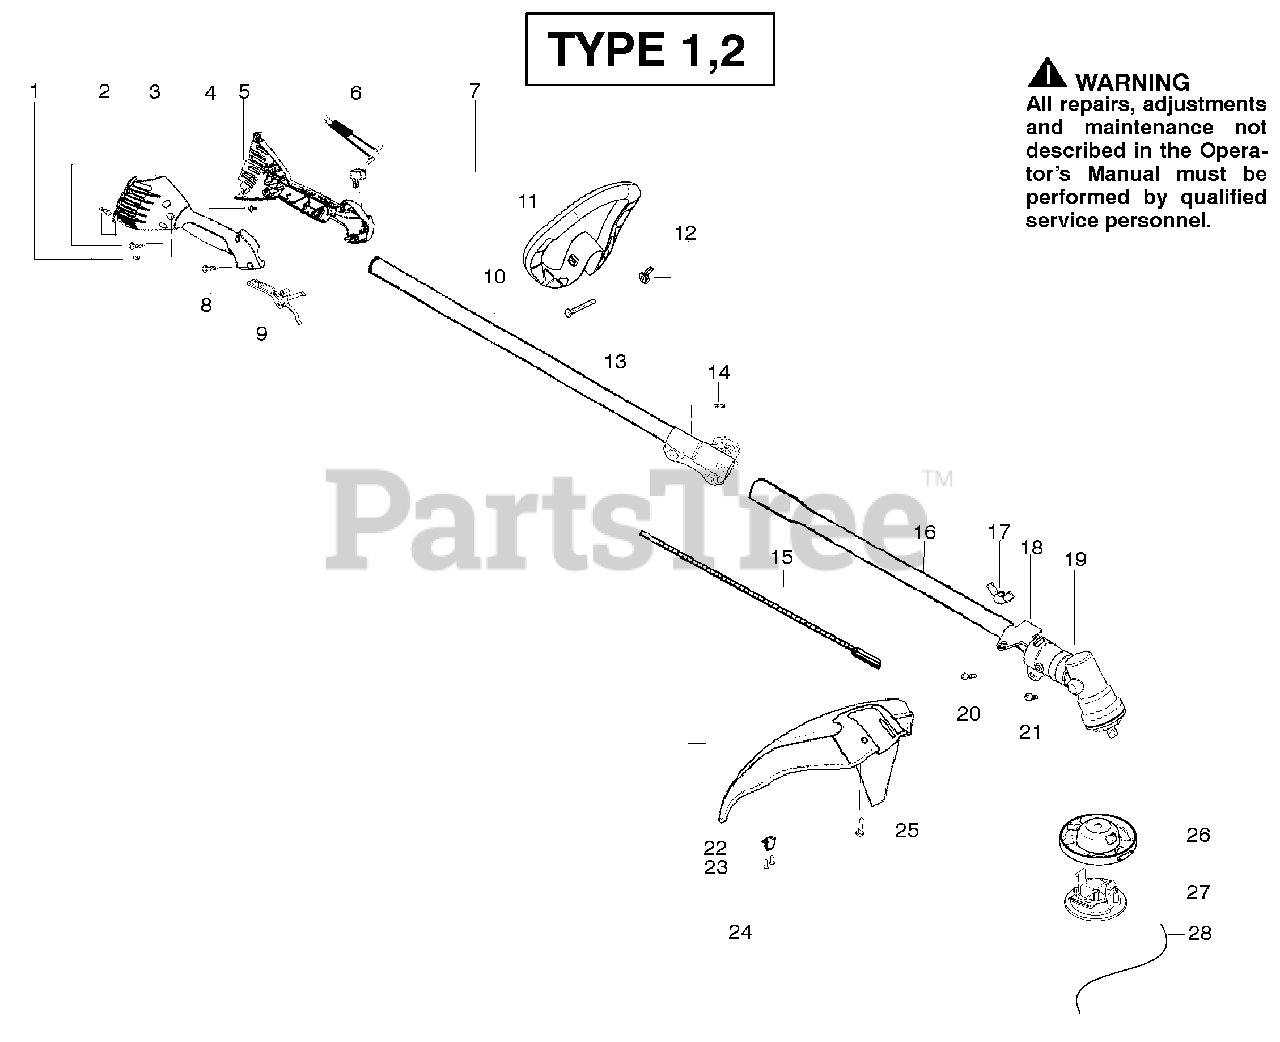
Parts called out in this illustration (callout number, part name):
1	Screw-alignment
3	Hsg.-Throttle right
4	Screw-Cable Retention
5	Hsg.-Left throttle
9	Lever-Throttle
11	Assy-Handle
12	Wingnut
13	Kit-Upper Shaft
15	Shaft-Flex (lower)
16	Kit-Lower Shaft
17	Wingnut
18	Bracket-Shield
24	Kit-Shield Assy.
26	Head-Fixed Line
27	Cap-Fixed Line
28	Accy-Line (12 pcs)
